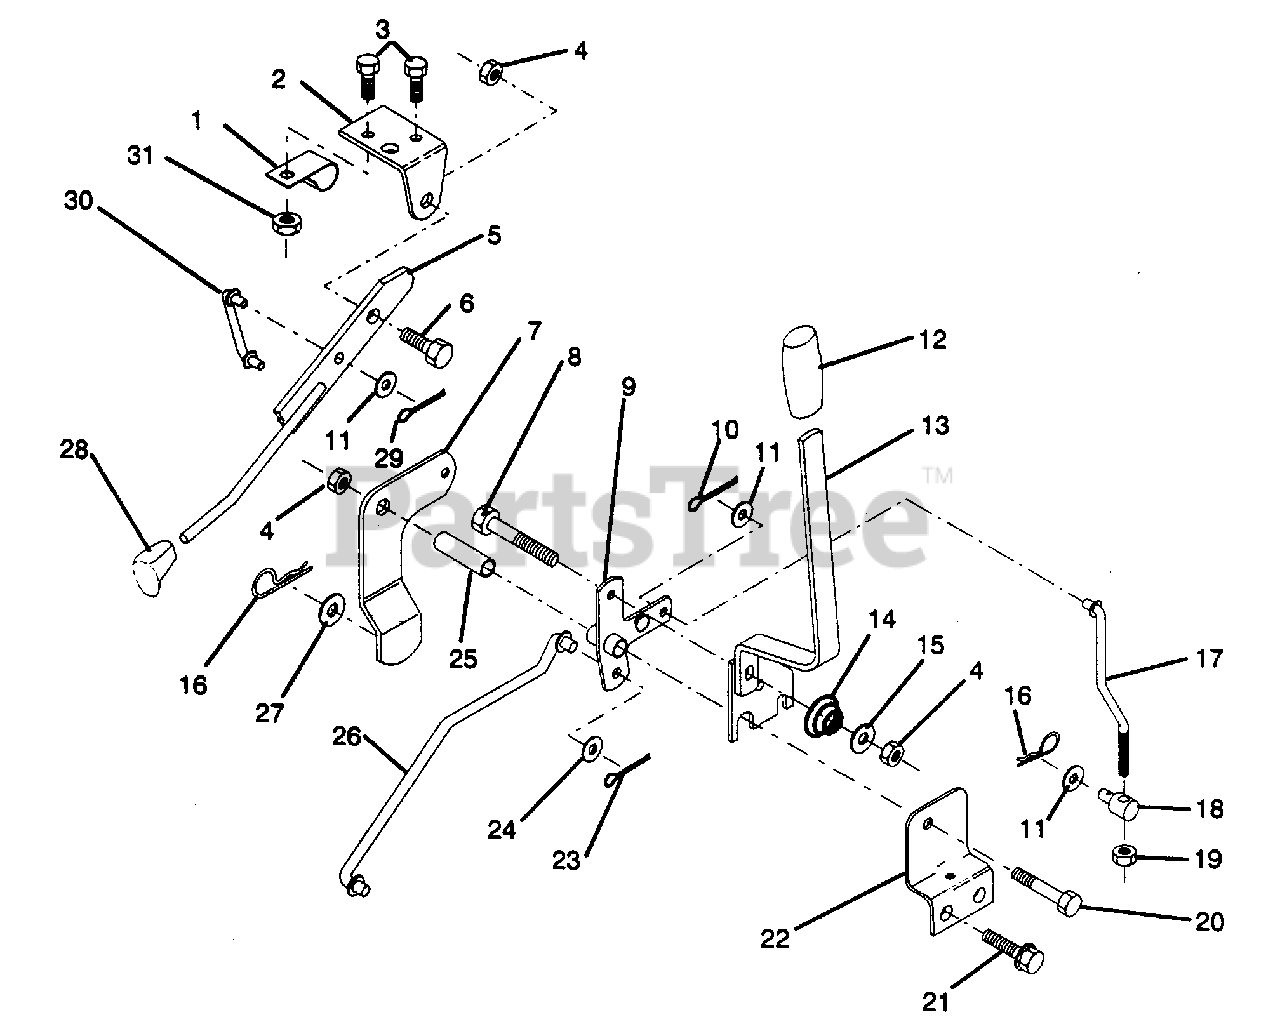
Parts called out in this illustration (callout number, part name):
1	Clip, Insulated (AYP part number)
2	Bracket, Mower Clutch (AYP part number)
3	Bolt, Fin. Hex 1/4-20 Unc x 1/2 Gr.5 (AYP part number)
4	Nut, Crownlock 3/8-16 UNC
5	Assembly, Clutch Lever (AYP part number)
6	Bolt, Shoulder (AYP part number)
7	Assembly, Mower Clutch Arm (AYP part number)
8	Bolt, Hex 3/8-16 UNC x 2 1/4 (AYP part number)
9	Assembly, Bellcrank Lift (AYP part number)
10	Pin, Cotter 1/8 x 3/4 (AYP part number)
11	Washer, 13/32 x 13/16 x 16 Ga. (AYP part number)
12	Grip, Handle (AYP part number)
13	Assembly, Lift Handle (AYP part number)
14	Spring, Compression (AYP part number)
15	Washer, 13/32 x 3/4 x 12 Ga. (AYP part number)
16	Retainer, Spring (AYP part number)
17	Link, Front Lift (AYP part number)
18	Threaded, Trunnion 3/8-16 (AYP part number)
19	Nut, Hex Jam 3/8 x 16 UNC (AYP part number)
20	Bolt, Fin. Hex 3/8-16 UNC x 2 3/4 (AYP part number)
21	Screw, Hex Thdrol. 5/16-18 x 1/2 (AYP part number)
22	Bracket, Mower Height (AYP part number)
23	Pin, Cotter 1/8 x 1 (AYP part number)
24	Washer 17/32 x 1 x 16 Ga. (AYP part number)
25	Tube, Spacer (AYP part number)
26	Rod, Mower Lift (AYP part number)
27	Washer, 13/32 x 13/32 x 16 Ga. (AYP part number)
28	Knob (AYP part number)
29	Pin, Cotter 3/32x3/4 (AYP part number)
30	Link, Mower Clutch (AYP part number)
31	Nut, Crownlock 1/4-20 (AYP part number)
